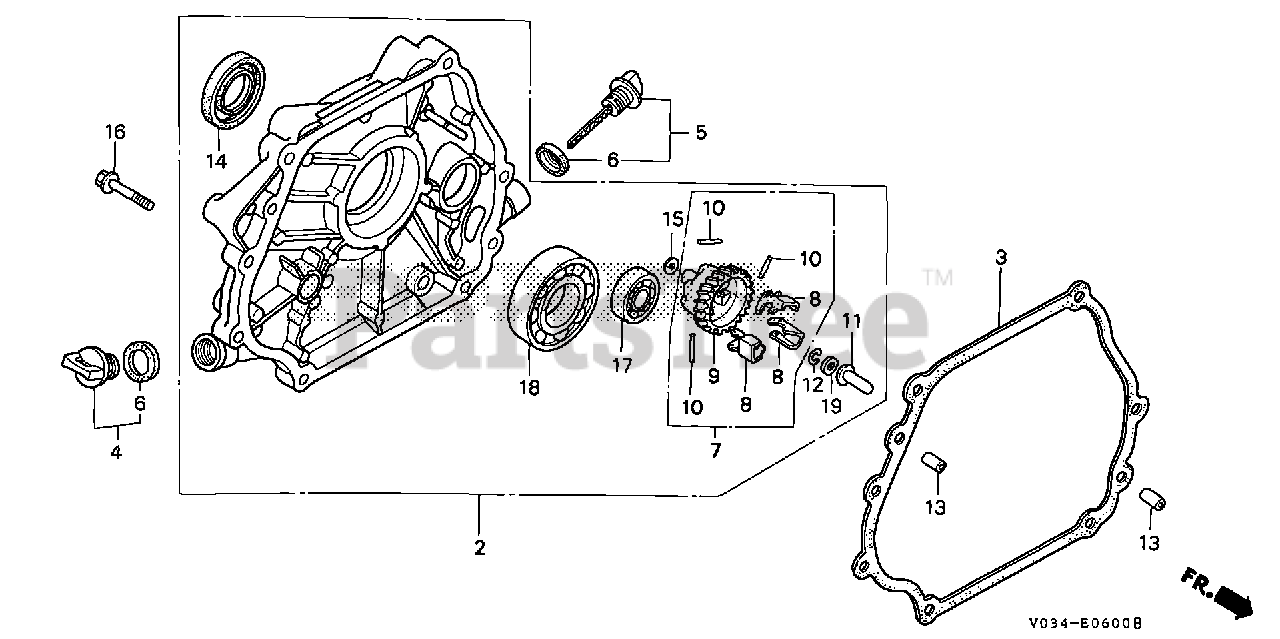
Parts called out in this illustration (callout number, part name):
2	COVER ASSY., CRANKCASE
3	GASKET, CASE COVER
4	CAP ASSY., OIL FILLER
5	CAP ASSY., OIL FILLER
6	GASKET, OIL FILLER CAP
7	GOVERNOR ASSY.
8	WEIGHT, GOVERNOR
9	HOLDER, GOVERNOR WEIGHT
10	PIN, GOVERNOR WEIGHT
11	SLIDER, GOVERNOR
12	CLIP, GOVERNOR HOLDER
13	PIN, DOWEL (8X12)
14	OIL SEAL (35X52X8)
15	WASHER, PLAIN (6MM)
16	BOLT, FLANGE (8X40)
17	BEARING, RADIAL BALL (6202)
18	BEARING, RADIAL BALL (6207)
19	WASHER (6X16)
